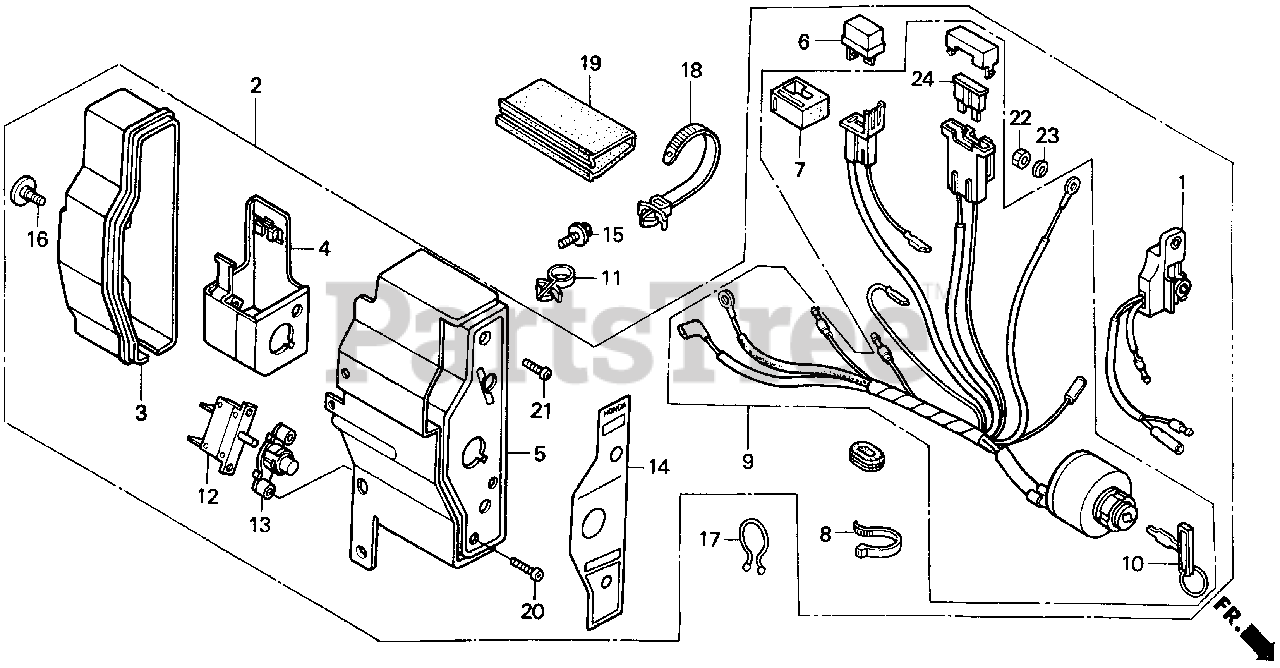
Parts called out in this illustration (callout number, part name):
1	ALERT UNIT, OIL (SEL)
2	BOX ASSY., CONTROL (3A) *R8* (EXTERNAL-ALERT) (BRIGHT RED)
2	BOX ASSY., CONTROL (EXTERNAL-ALERT/3A) *R8* (BRIGHT RED)
3	CASE, CONTROL
4	BRACKET, CASE MOUNTING
5	PANEL, CONTROL *R8* (BRIGHT RED)
6	RECTIFIER ASSY., SILICON (STANLEY)
7	SUSPENSION, CONNECTOR
8	BAND
9	SWITCH ASSY., COMBINATION
10	KEY
11	HOLDER, STOP SWITCH WIRE
12	PROTECTOR, CIRCUIT (3.5A)
13	LENS ASSY., PROTECTOR
14	PANEL, CONTROL BOX (EXTERNAL)
14	PANEL, CONTROL BOX (EXTERNAL-ALERT)
15	BOLT, FLANGE (6X12) (CT200)
16	SCREW, SPECIAL (6X12)
17	CLIP, PURSE LOCK
18	STRAP, CABLE (118MM) *NH1L* (BLACK)
19	TUBE, FASTENER (30)
20	SCREW, PAN (3X12)
21	SCREW, PAN (4X12)
22	NUT, HEX. (4MM)
23	WASHER, SPRING (4MM)
24	FUSE, BLADE (15A)
